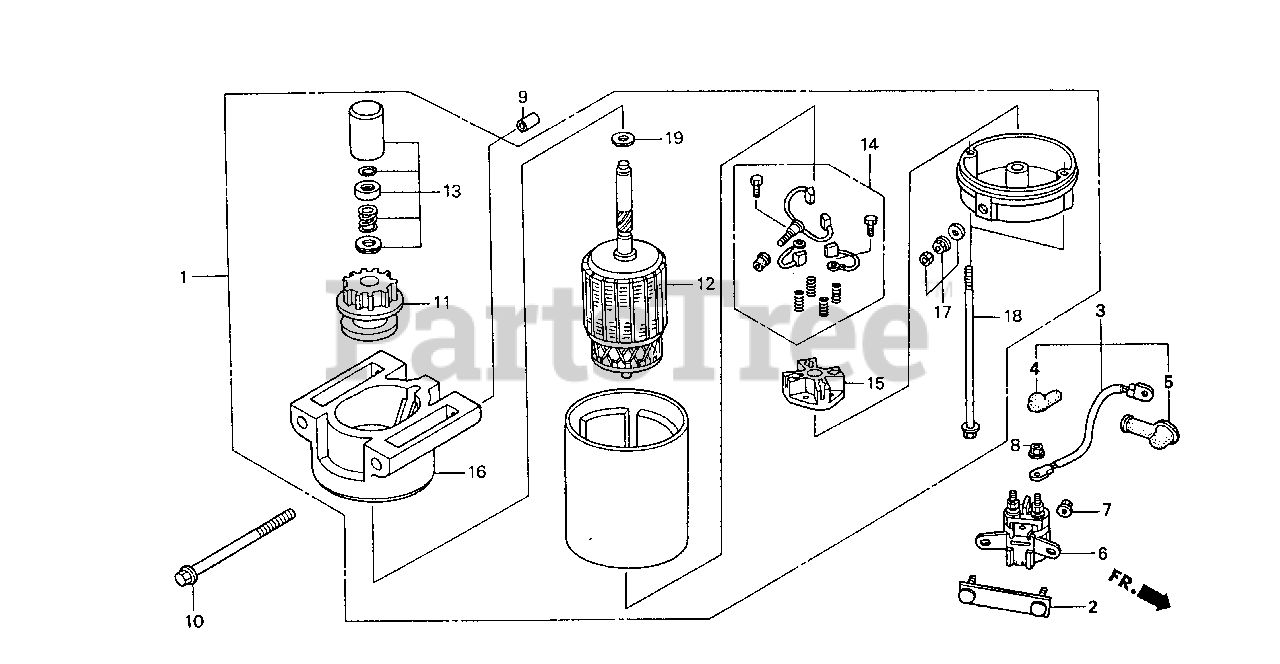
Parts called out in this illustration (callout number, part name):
1	MOTOR ASSY., STARTER
2	BRACKET, STARTER MAGNETIC SETTING
3	CABLE, MAGNET SWITCH
4	COVER A, MAGNETIC SWITCH
5	COVER, STARTER MOTOR TERMINAL
6	SWITCH ASSY., STARTER MAGNETIC
7	NUT-WASHER (6MM)
8	NUT-WASHER (6MM)
9	PIN, DOWEL (10X12)
10	BOLT, FLANGE (8X110)
11	GEAR SET, PINION
12	ARMATURE
13	STOPPER SET, PINION
14	BRUSH SET
15	HOLDER, BRUSH
16	BRACKET, FR.
17	NUT SET, TERMINAL
18	BOLT, THROUGH
19	WASHER, THRUST
